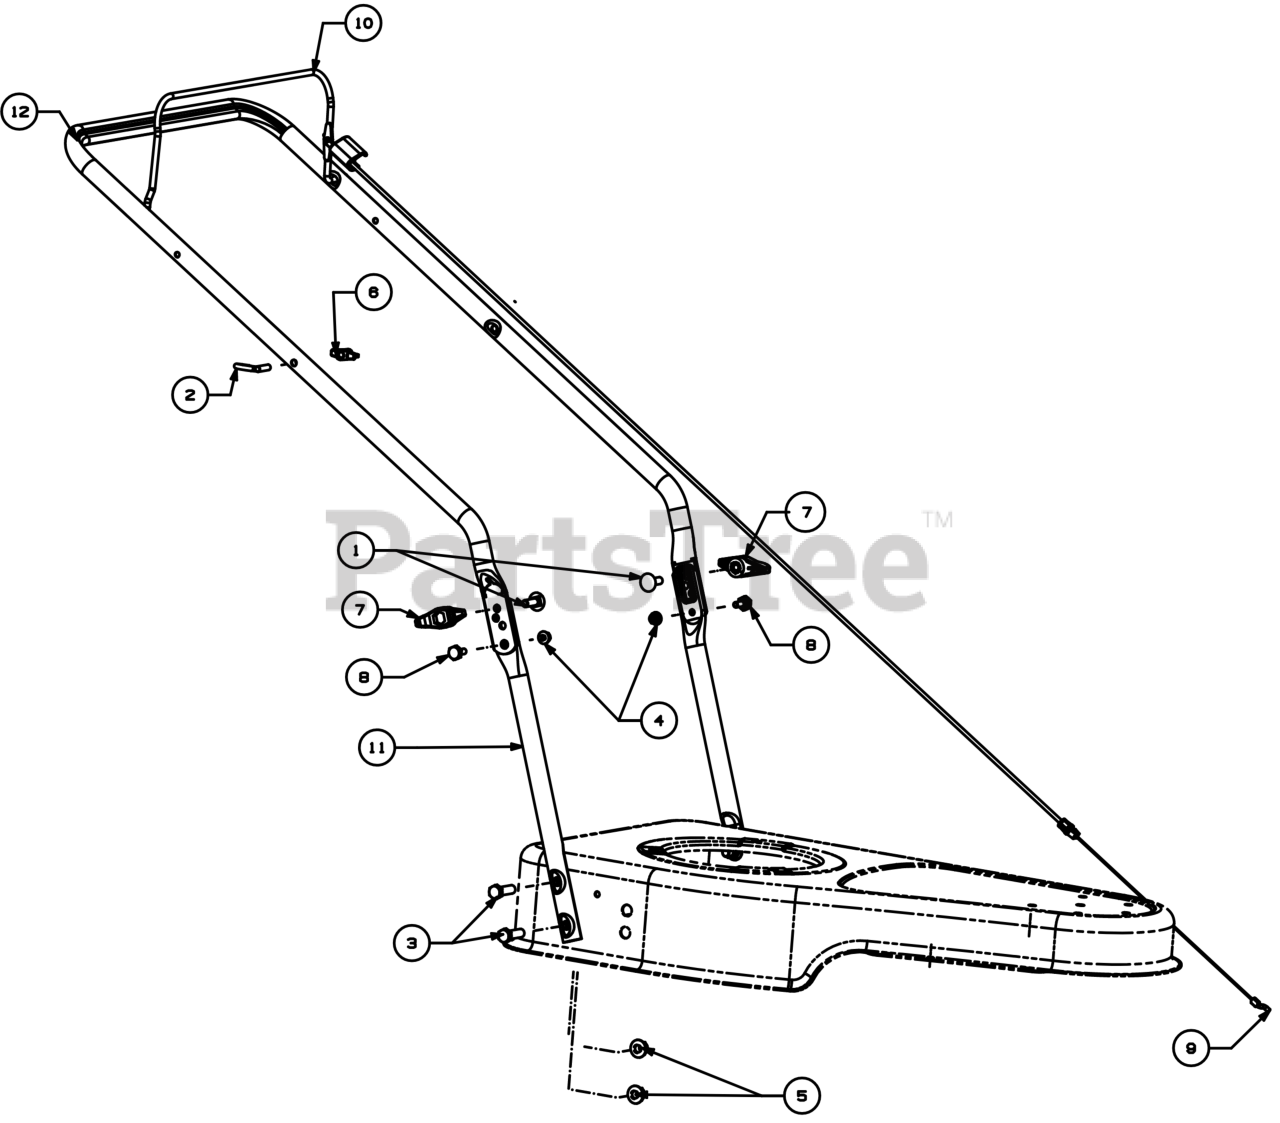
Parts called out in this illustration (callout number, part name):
1	SCREW 5/16-18 x 1.00 GR5
2	EYEBOLT 1/4-20
3	SCREW 3/8-16 x 1.25 GR5
4	FLANGE LOCK NUT
6	HANDLE KNOB
7	WING KNOB 5/16-18
8	SHOULDER SCREW
9	CONTROL CABLE
12	HANDLE (UPPER)
